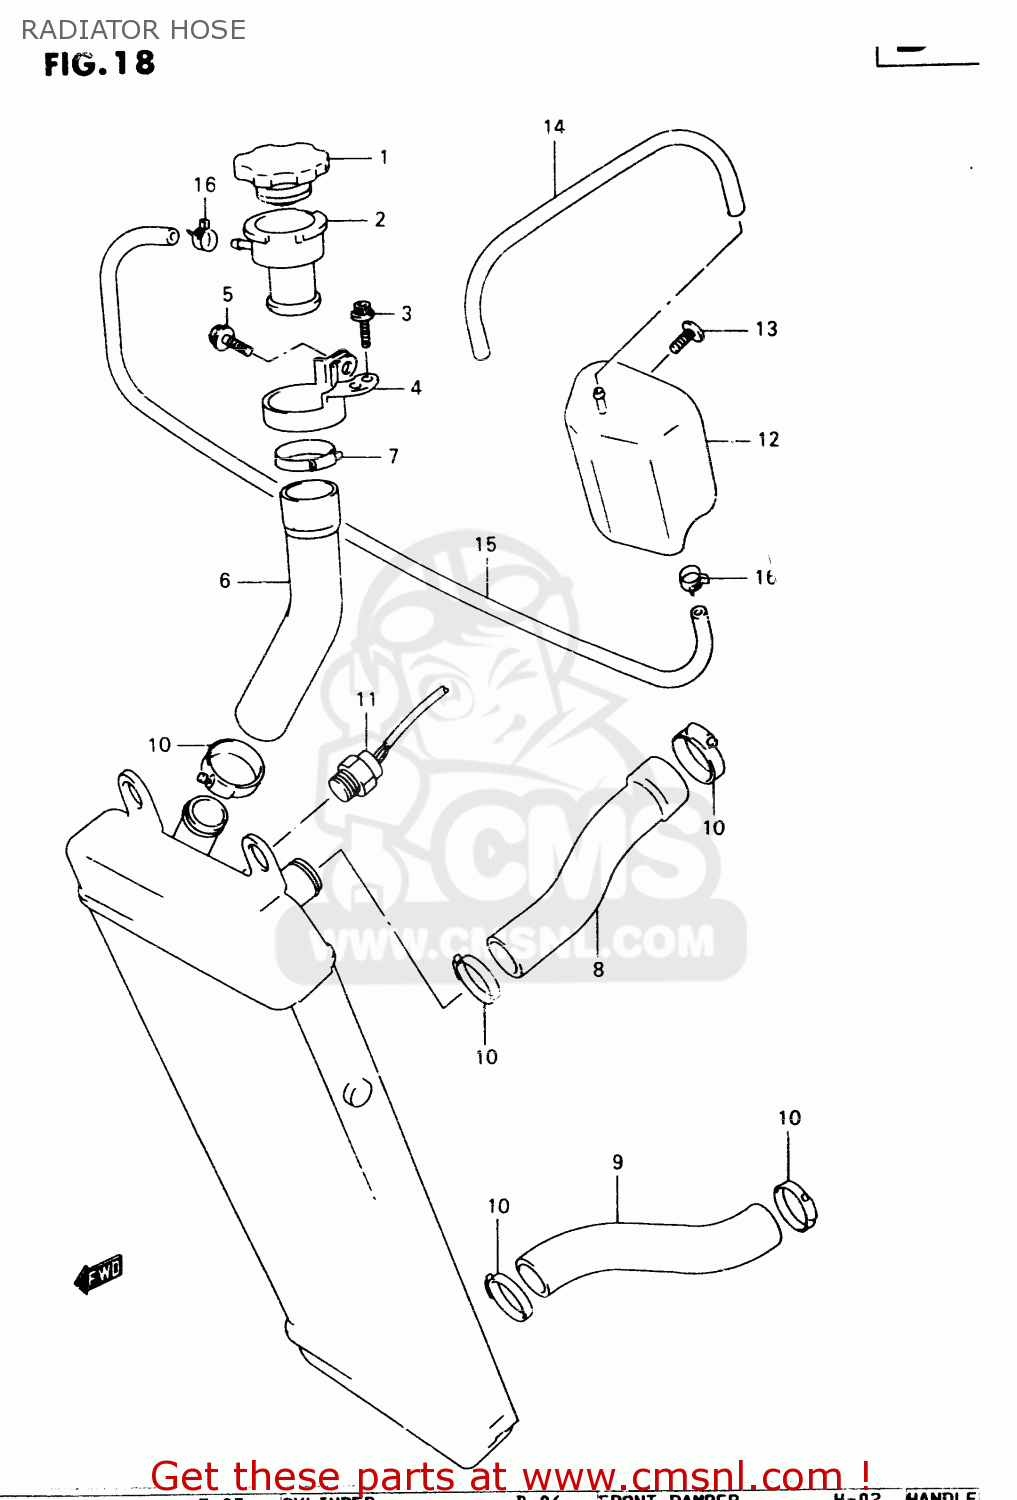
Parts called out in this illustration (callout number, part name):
1	CAP COMP,RADIATOR 1.1
2	CONDUCTION,RADIATOR
3	BOLT MAGNETO S
4	BRACKET,CONDUCTION
5	BOLT
6	HOSE,CONDUCTION
7	CLAMP
8	HOSE,RADIATOR INLET
9	HOSE,RADIATOR OUTLET
10	CLAMP
11	SWITCH,RADIATOR FAN
12	TANK,RESERVOIR
13	SCREW 6X12
14	HOSE,RESERVOIR TANK OUTLET
15	HOSE,RESERVOIR TANK INLET
16	CLIP
